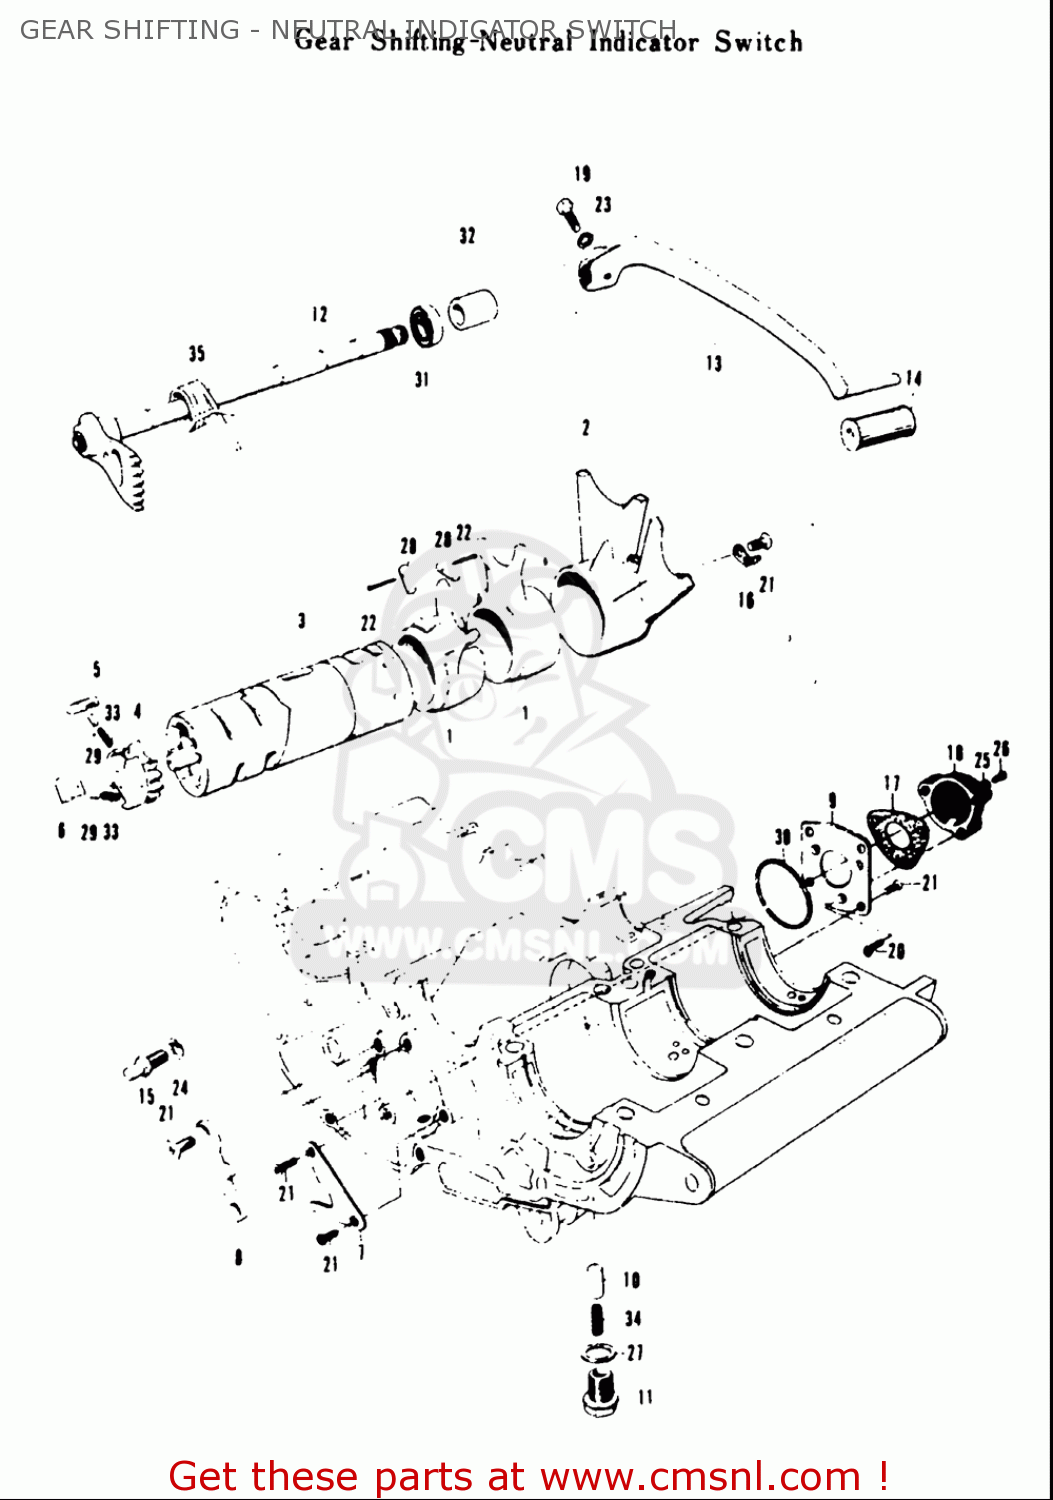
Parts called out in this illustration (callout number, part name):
4	GEAR,GEAR SHIFT CAM DRIVEN
5	PAWL,GEAR SHIFT NO.2
6	PAWL,GEAR SHIFT NO.1
7	LIFTER,GEAR SHIFT PAWL
11	HOUSING,GEAR SHIFT CAM STOPPER
14	RUBBER,GEAR SHIFT PEDAL
15	STOPPER,GEAR SHIFT ARM
16	CONTACT,GEAR SHIFT SWITCH
18	NEUTRAL SWITCH BODY
19	BOLT
23	WASHER,LOCK
24	WASHER,LOCK
25	WASHER
27	GASKET(14X19.2X2) (NAS)
28	PIN
29	PIN(5X8)
30	O RING(D:2.6,ID:47.4)
31	SEAL,OIL (12X22X9)
32	CUSHION
33	SPRING
34	SPRING
35	SPRING
